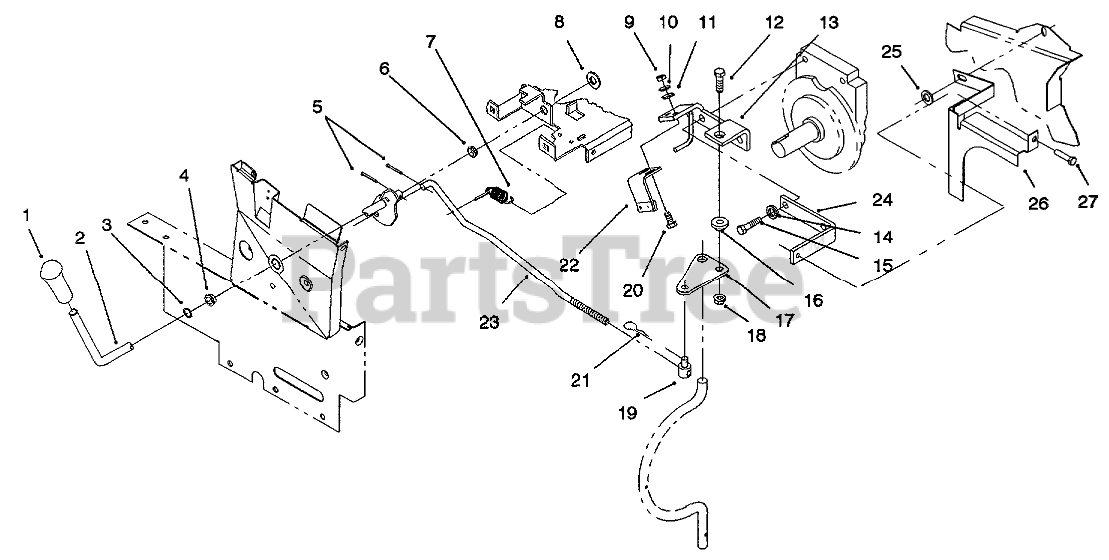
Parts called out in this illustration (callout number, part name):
2	PTO CLUTCH LEVER ASM
3	RING-EXT GRIP
4	BUSHING-NYLINER
5	PIN-COTTER
6	NYLINER BUSHING
7	SPRING
8	SHIM-WASHER
9	NUT-JAM
10	WASHER-LOCK
11	WASHER-FLAT
13	BRCKET-ENGINE (BLACK)
14	WASHER-LOCK
15	SCREW-HH
16	SPACER-LIFT LINK
17	PLATE
18	NUT-LOCK, NI
19	TRUNNION
20	SCREW-CARR
21	PIN-HAIR
22	BRAKE ASM
23	ROD-PTO CLUTCH
24	Bar-Support
25	WASHER-PLAIN
27	Bolt
